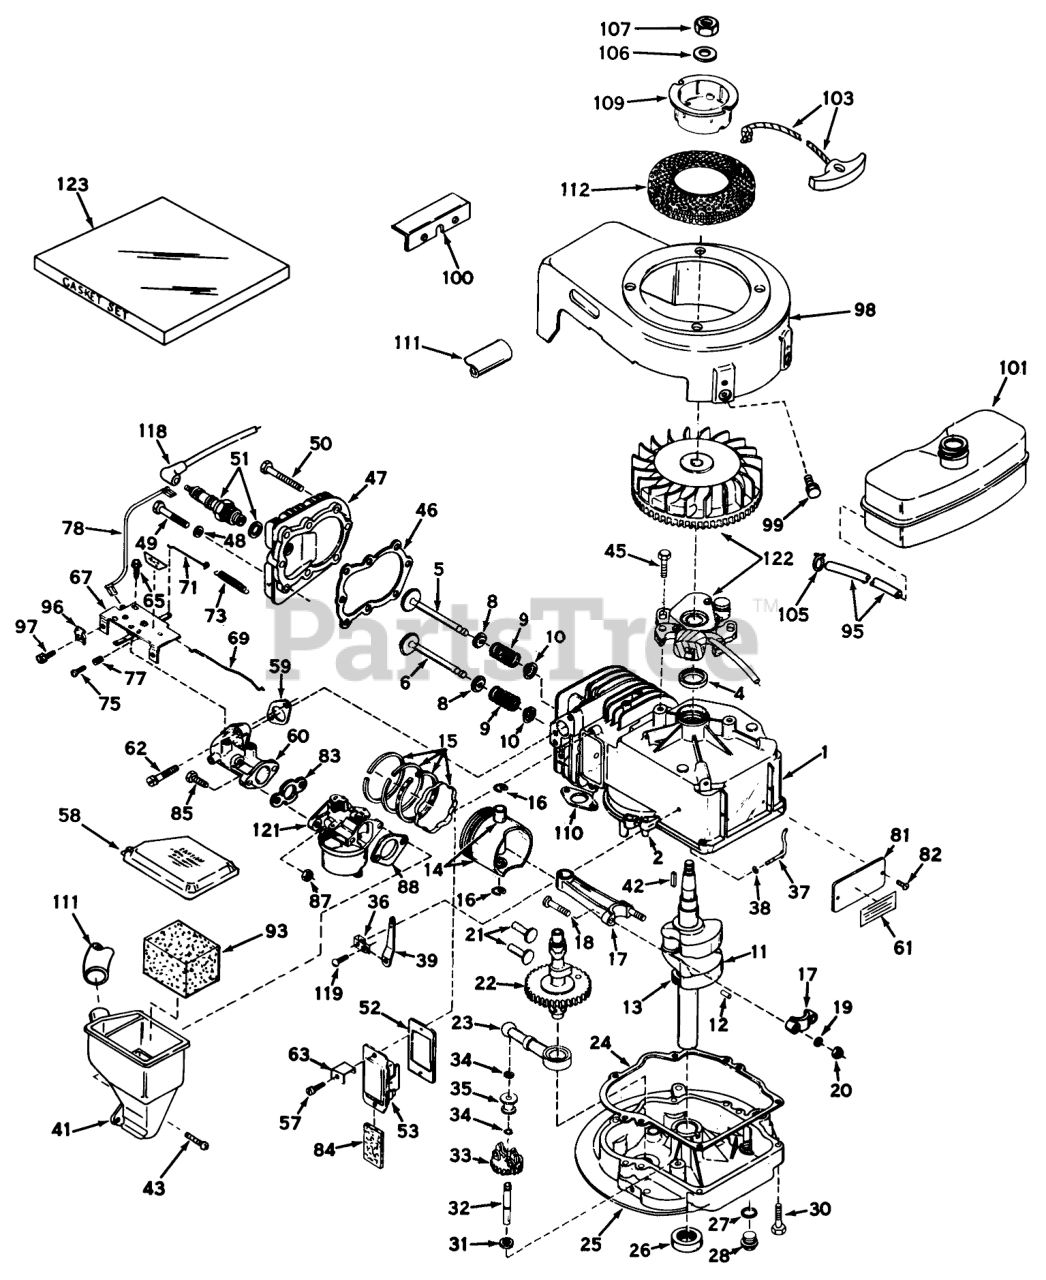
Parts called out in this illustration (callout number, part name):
1	Cylinder Assy. (Incl. Nos.2, 4)
2	Pin-Dowel
4	OIL SEAL
5	Valve, Intake (Std.)(Incl. Nos. 8, 9 & 10)
5	Valve, Intake (1/32" oversize)(Incl. Nos. 8, 9 & 10)
6	Valve, Exhaust (Std.)(Incl. Nos. 8, 9 & 10)
6	Valve, Exhaust (1/32"0versize)(Incl. Nos. 8, 9 & 10)
8	Cap-Upper Valve Spring
9	Spring-Valve
10	Cap-Valve, Spring
11	Crankshaft Assy. (Incl. Nos. 12 & 13)
12	Pin, Groove
13	Gear, Crankshaft
14	Piston & Pin Assy.(Incl. 2 of No. 16)(Std.)
14	Piston & Pin Assy.(Incl. 2 of No. 16)(.010 Oversize)
14	Piston & Pin Assy.(Incl. 2 of No.16)(.020 Oversize)
15	Ring Set, Piston (Std.)
15	Ring Set, Piston (.010 o.s.)
15	Ring Set, Piston (.020 o.s.)
16	Ring-Retaining, Piston Pin
17	Rod Assy., Connecting (Incl. Nos. 18, 19 & 20)
18	Bolt, Connecting
20	LOCKNUT
21	Lifter-Valve
22	Camshaft
23	Oil Pump ASM
24	Gasket, Mounting
25	Flange Assy., Mtg. (Incl. Nos.26, 27, 28 & 32)
26	Seal Oil
27	Gasket-Oil Drain
28	Plug Oil Drain
30	Screw (1/4-20 x 1-1/4)
31	Washer-Flat
32	Shaft-Governor
33	Governor Gear ASM
34	Ring-Retaining
35	Spool-Governor
36	Clamp-Lever, Governor
37	Rod, Governor (Incl. No.38)
38	Washer-Flat
39	Governor Lever
41	Body, Air Cleaner
42	Key Flywheel
43	Screw, Fil. Hd. Sems
46	Gasket-Cylinder Head
47	CYLINDER HEAD
49	Screw
50	Screw Hex Hd. Cap
51	SPARK PLUG
52	Gasket Breather
53	Breath. Assy. (Incl. Nos. 52, 84)
58	Cover, Air Cleaner
59	Gasket, Intake
60	Pipe, Intake
61	480B GIL SNWTHWR O/
62	Screw, Fil. Hd. Sems
63	Retainer Clip
65	Screw (10-24 x 9/16)
67	Control Assy., Speed
69	Link, Throttle to Governor
71	Link-Governor
73	Spring, Governor
75	Screw
77	Spring-Compression
78	Wire, Ground
81	IDENTIFICATION PLATE
84	Element-Breather
85	Screw (1/4-28 x 7/8)
87	Nut and Lock Washer (1/4-28)
88	Gasket-Air Cleaner
93	Element, Air Cleaner
95	Line-Fuel (8.62)
96	Conduit
97	Screw (10-32 x 3/8)
98	Housing, Blower
99	Screw (1/4-20x19/32)
100	Bracket, Shroud
101	Tank, Fuel (Including No. 102)
103	Rope Assy., Starter
105	Clamp-Line, Fuel
106	Washer
107	Hex Nut
109	Pulley Starter
110	Gasket Exhaust
111	Tube, Air Cleaner
112	Screen, Air
118	Cover-Spark Plug
119	Screw
121	Carburetor
122	Magneto
123	Gasket Set
